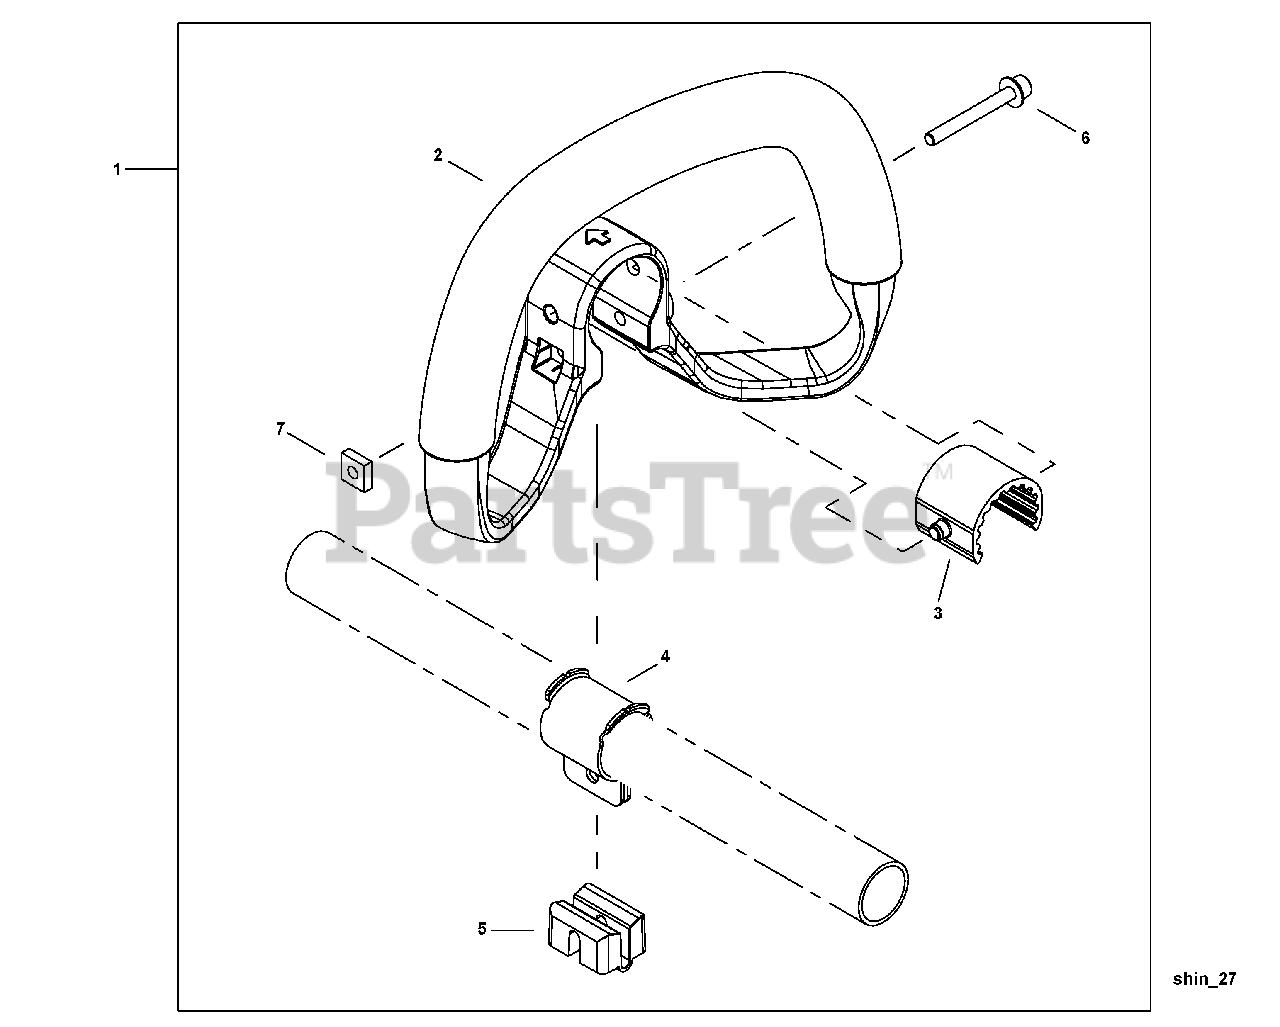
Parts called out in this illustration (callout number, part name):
1	HANDLE ASSY
2	HANDLE
3	CUSHION
4	CLAMP
5	BLOCK, SPACER
6	SCREW - 5X45
7	NUT - 5
